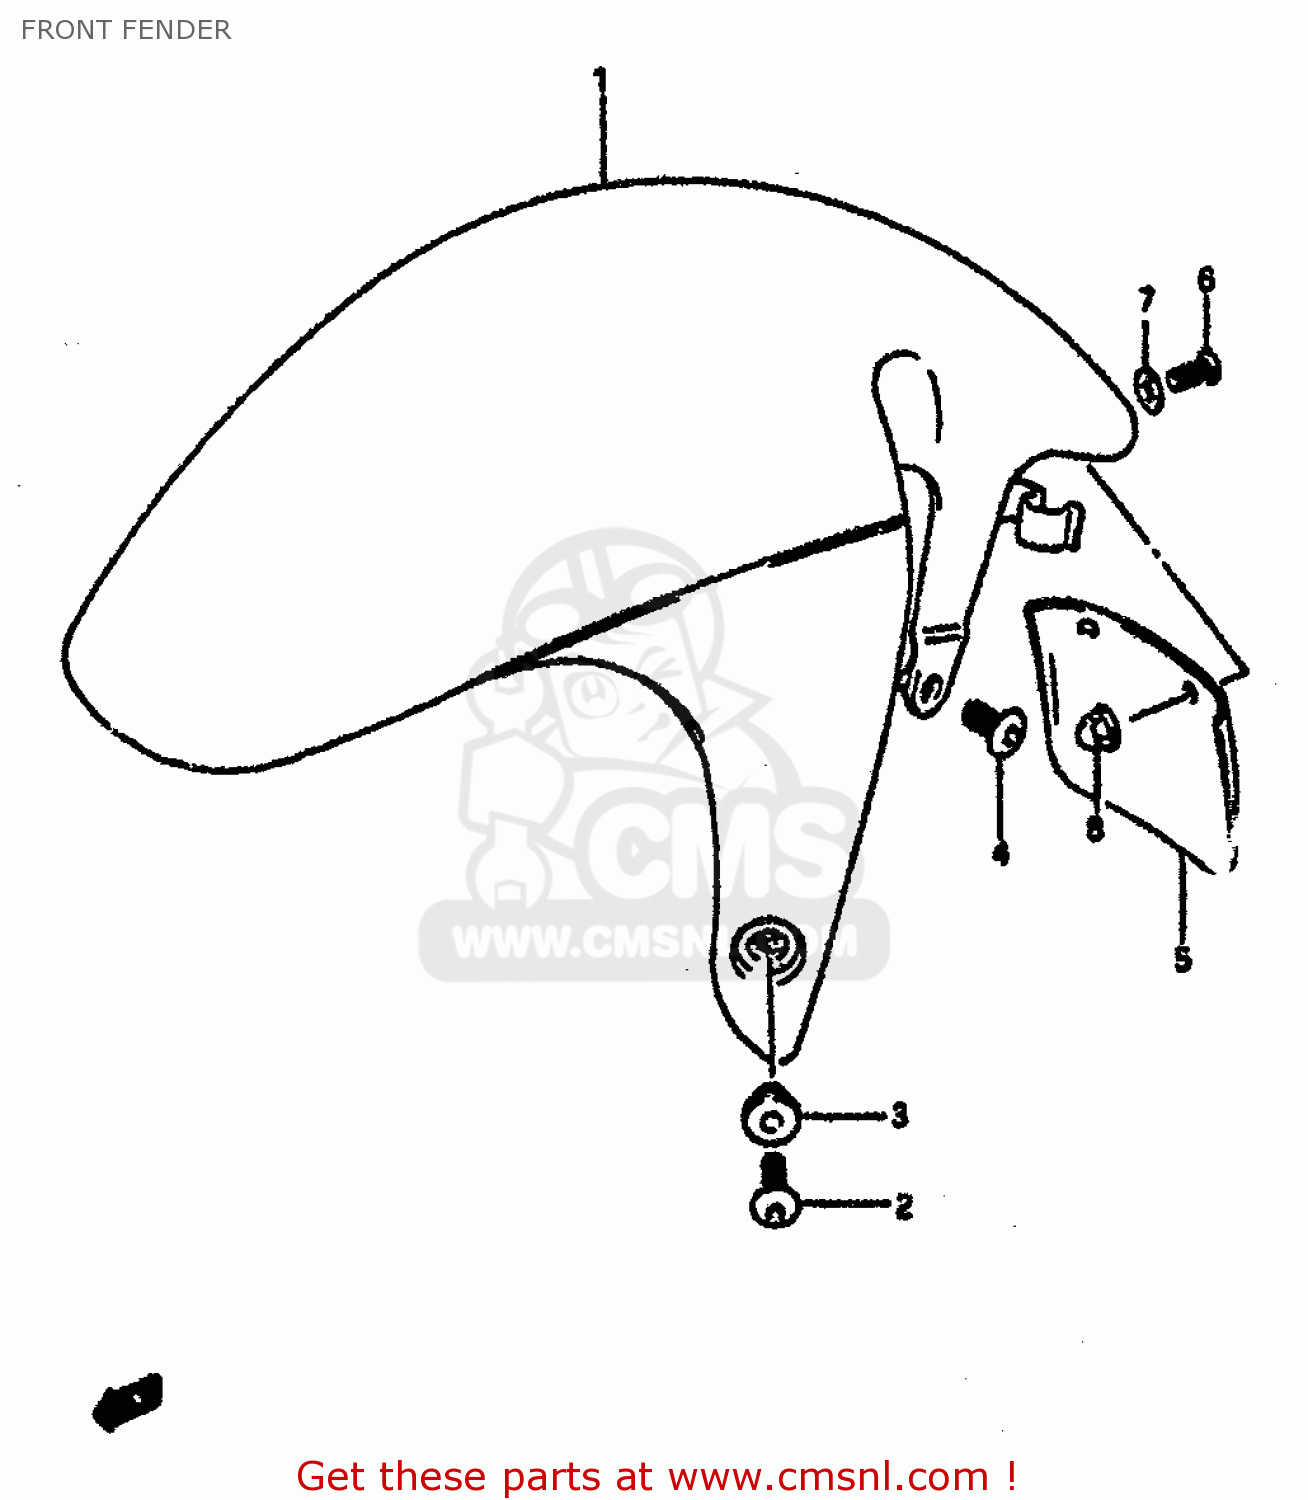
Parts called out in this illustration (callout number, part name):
1	FENDER,FRONT
2	SCREW(6X16)
3	WASHER(6.3X16X1.5)
4	SCREW(8X16)
5	MUD GUARD,FR.F
6	SCREW M5X12 DIN 7985/N
7	WASHER
8	NUT 5MM
